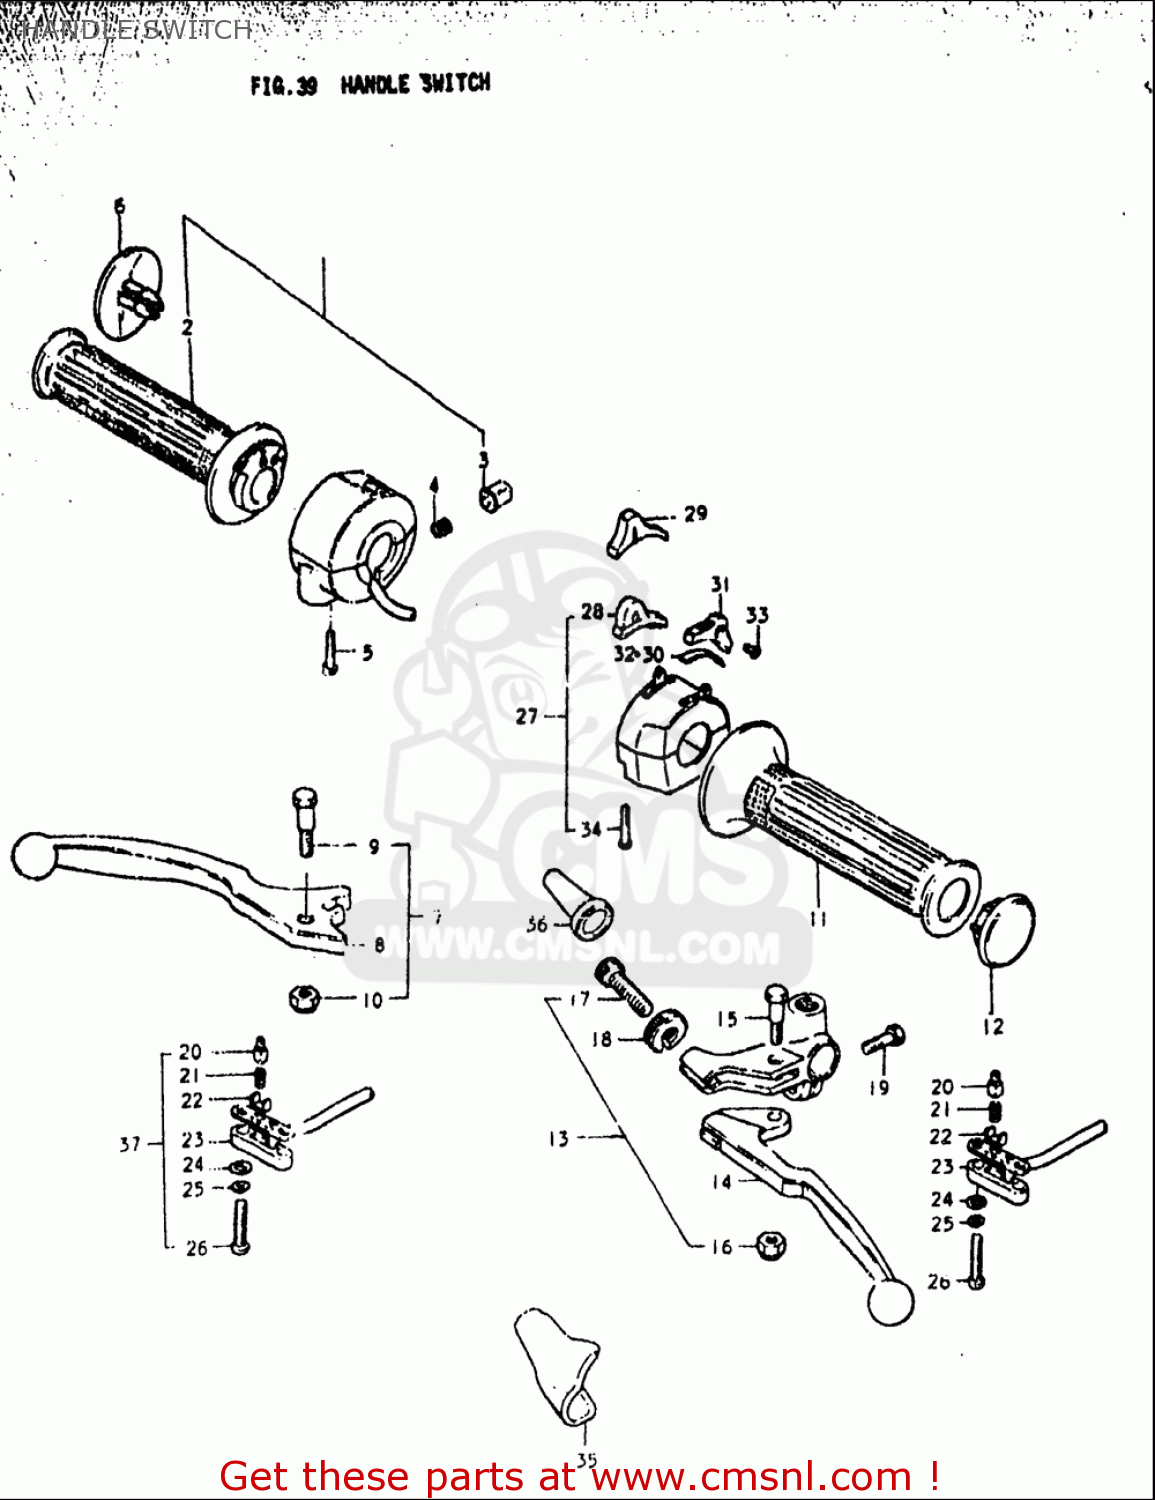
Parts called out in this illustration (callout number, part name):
1	CASE ASSEMBLY,THROTTLE
2	GRIP,THROTTLE
3	BUTTON
4	SPRING
5	SCREW
6	CAP,GRIP END
7	LEVER,BRAKE
8	LEVER,BRAKE
9	BOLT
10	NUT 6MM
11	GRIP,L
12	CAP,GRIP END
13	LEVER ASSY,CLUTCH
14	LEVER,CLUTCH
15	BOLT,LEVER PIVOT
16	NUT 6MM
17	ADJUSTER,CABLE
18	NUT,CABLE ADJUSTER
19	BOLT
20	CONTACT,SWITCH
21	CONTACT,SWITCH
22	CONTACT,SWITCH
23	COVER,FR BK TERMINAL BASE
24	WASHER
25	WASHER,LOCK
26	SCREW
27	SWITCH ASSEMBLY,HANDLE,LEFT
29	KNOB,HANDLE SWITCH
30	PLATE,SWITCH KNOB
31	KNOB,DIMMER SWITCH
33	SCREW
34	SCREW
35	COVER,CLUTCH LEVER
36	BOOT,CLUTCH CABLE
37	SWITCH ASSY,STOP
